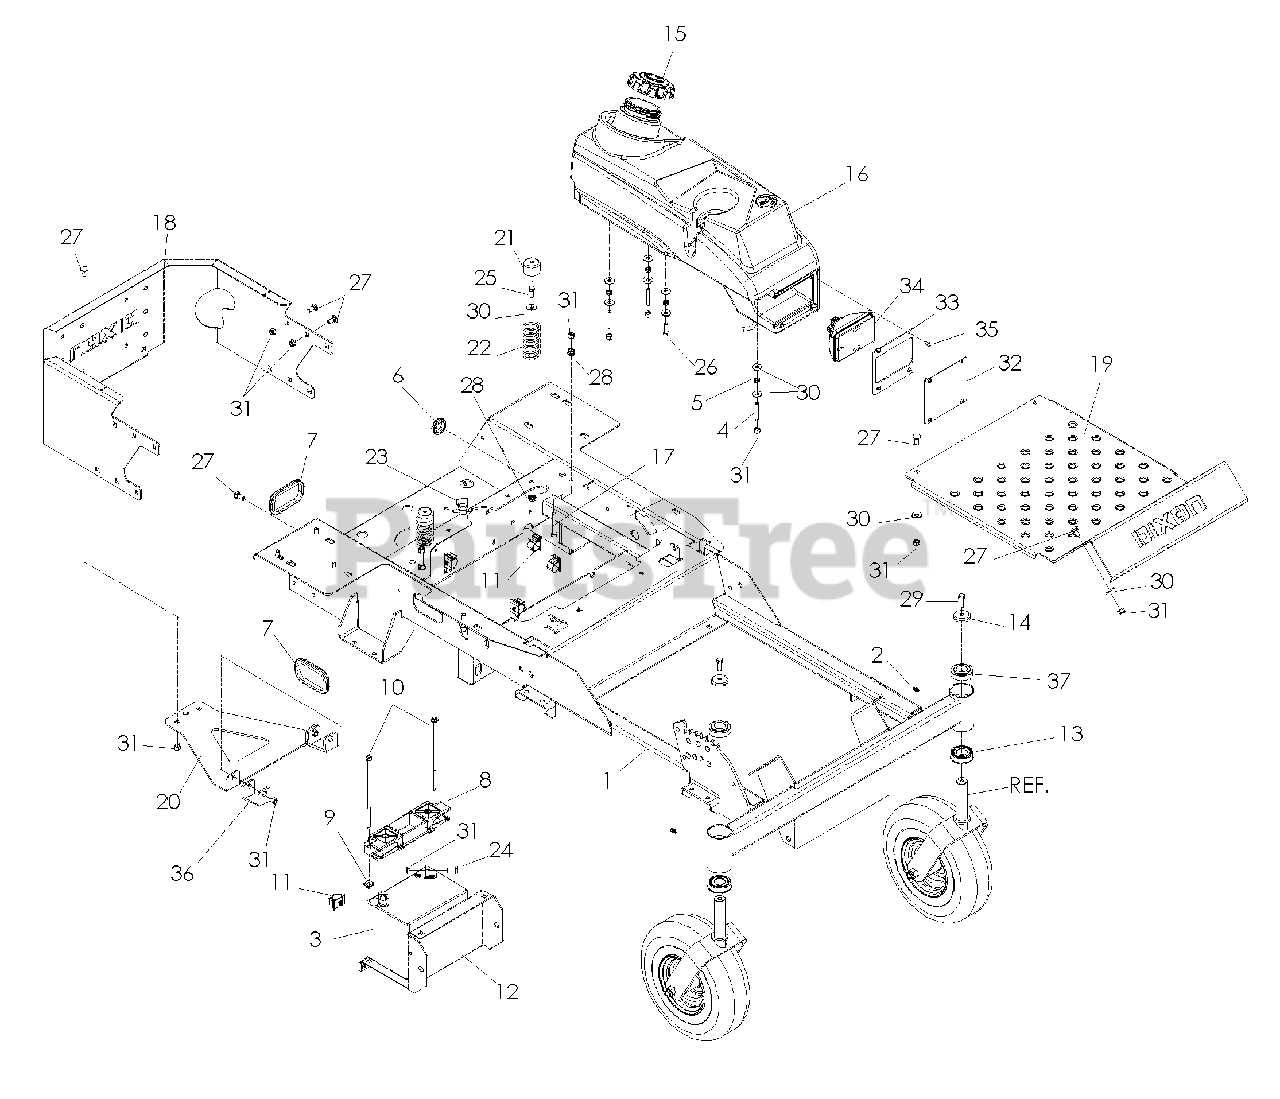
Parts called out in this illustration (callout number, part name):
1	FRAME W/DECALS RAM CE
2	ZERK, 3/16, DRIVE IN
3	BATTERY, 12 V 330 AMP TBR
4	STUD, 5/16C
6	RUBBER GROMMET
7	GROMMET
8	BATTERY HOLD DOWN
9	PUSH NUT-NYLON
10	BOLT - 1/4-20 X 7.5
11	PUSH-MOUNT WIRE CLIP
12	BATTERY TRAY
13	BEARING FLANGED
14	CASTER.PLUG
15	FUEL CAP ANTI-SPLASH
16	TANK, FUEL, LT
17	TAP BOLT 5/16C X 2 1/4
18	GUARD, REAR
19	FLOOR PAN WITH DECALS RAM
20	STRAP, REAR
21	SPRING CAP
22	SEAT SPRING
23	FUEL VALVE
24	HCS 5/16C X 3/4
25	SCREW 5/16C X 1 HEX CAP
26	HCS 5/16C X 1
27	BOLT 5/16C X 3/4" CARRIAGE
28	NUT 5/16C WHIZ
29	HHCS 1/2-13 X 1
30	WASHER 5/16 FLAT
31	NUT 5/16 NYLOC
32	PANEL, LIGHT DELETE
33	PLATE LIGHT
34	LIGHT
35	SCR #10-24 X 3/8 SKT HD BLK OX
36	EXTENSION, STRAP
37	BUSHING, CASTER
